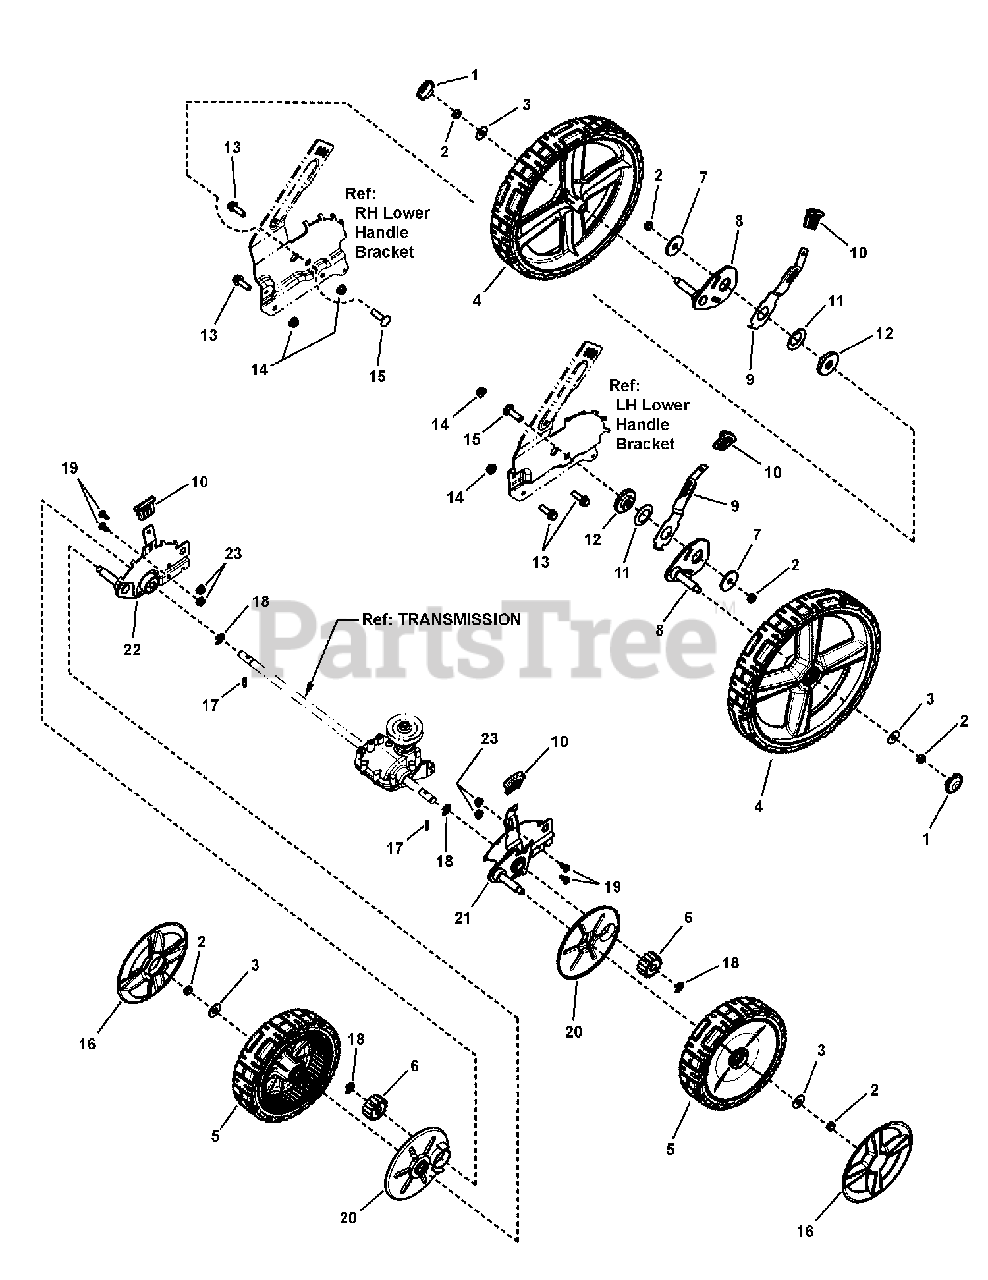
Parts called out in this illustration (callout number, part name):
1	HUBCAP, 12" Wheel, Snapper Cool Gray
2	NUT, 3/8-16 Hex Center Lock, GR 5, YZ
3	WASHER, 1" O.D. x .387 I.D., Flat
4	WHEEL, 12" x 2" w/Snapper Tread, Snapper Cool Gray
5	ASSEMBLY, Wheel, 8" x 2" Drive w/Snapper Tread, Charcoal Gray
6	GEAR, Pinion, 22" WBM, Front Wheel Drive
7	WASHER, 13/32 x 1-1/2" x .120 Flat, YZ
8	ASSEMBLY, Rear Wheel Bracket, Hi-Wheel (staked)
9	LEVER, Front, Height-Of-Cut, 22"
10	GRIP, Height Latch - Black (1.7" Wide)
11	WASHER, Belleville, 1.01-1.64
12	BUSHING, Pivot, Hi-Wheel, Rear
13	BOLT, 5/16-18 x 1" Hex Flange lock, GR 5, YZ
14	NUT, 5/16-18 Hex Flange Lock, GR 5, YZ
15	BOLT, 3/8-16 x 1-1/4" Round Head Square Neck Carriage, GR 5 YZ
16	HUBCAP, 8" & 9" Spoked Wheel, Snapper Cool Gray
17	DRIVE PIN, 22" WBM
18	RETAINING RING, .392 Ext.
19	SCREW, 1/4-20 x .550" Pan Head Self-Tap (Torx)
20	SHIELD, Dust, 22" WBM, Front Wheel Drive
21	ASSEMBLY, Height-of-Cut, LF, 22" WBM, Propelled
22	ASSEMBLY, Height-of-Cut, RF, 22" WBM, Propelled
23	NUT, 1/4-20 Hex Flange Lock, YZ
